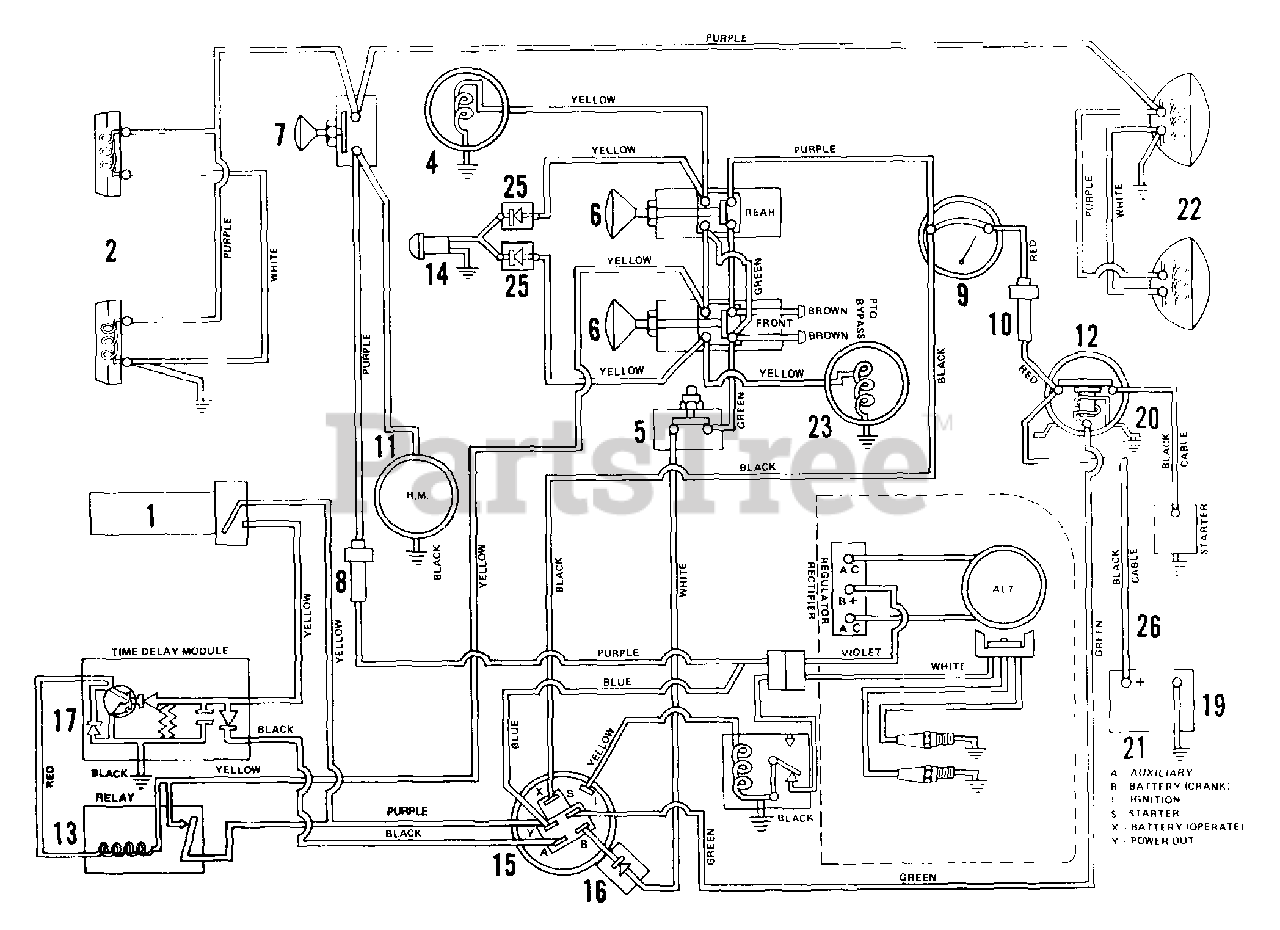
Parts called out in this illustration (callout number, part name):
1	SWITCH SEAT
2	TAIL LIGHT ASSEMBLY W/BULLET
2	TAIL LIGHT LENS
2	MALE DISCONNECT ADAPTER
2	SCR-MCH 10-24X.50 SLTR PL
2	WSHR-LK 10X.047 MED PL
2	NUT-HEX 10-24 PL
4	ELECTRIC CLUTCH
5	SAFETY SWITCH
5	CONNECTOR
5	NUT-HEX .625-32 PL
6	CLUTCH SWITCH
6	CONNECTOR
6	WSHR-FL-STL .382X.812X.023 PL
7	LIGHT SWITCH
7	CONNECTOR
7	WSHR-FL-STL .382X.812X.023 PL
8	7 Amp Fuse
9	AMMETER
9	WSHR-LK-EXT #10 ID X .022
9	NUT 10-32 PL
10	30 Amp Fuse
11	HOUR METER
12	SOLENOID
12	WSHR-LK-EXT #10 ID X .022
12	NUT 10-32 PL
12	WSHR-LK-INT .313X.030 PL
12	NUT-JAM .312-24 PL
12	BLT-HEX .25-20X.75 PL GR2
12	BLT-HEX .25-20X1.00 GR2
12	WSHR-FL-STL.281X.62X.065 PL
12	WSHR-LK-EXT. 250 ID
13	RELAY
14	PTO INDICATOR LIGHT
14	LAMP SOCKET
14	SPEED NUT
15	SWITCH ASSEMBLY
15	CONNECTOR HOUSING
15	WSHR-LK-INT .563X.040 PL
15	NUT .562-24
16	DIODE ASSEMBLY
16	SCR-TAP .250-20X.50 HXSLHDPL
17	TIME DELAY MODULE
17	SCR-MCH 10-24X.50 SLTR PL
17	WSHR-LK 10X.047 MED PL
17	NUT-HEX 10-24 PL
19	GROUND CABLE .25X6.50X.31
19	BATTERY CABLE
19	WSHR-LK .250X.077 HVY PL
19	NUT-HEX .250-20 PL
20	STARTER CABLE .25X.35.25X.31
20	GROUND CABLE
21	BATTERY
22	HEAD LIGHT
22	HEAD LIGHT RETAINER RING
22	SCR-MCH 10-24X.50 SLTR PL
22	WSHR-FL-STL .250X.562X.049 PL
23	DIESEL CLUTCH ASSEMBLY
23	CLUTCH ASSEMBLY 1 1/8 BORE
23	CLUTCH ASSEMBLY 1-1/4 BORE
25	MOLDED DIODE PLUG 1 AMP
26	STARTER CABLE 6.75"
27	CONNECTOR
